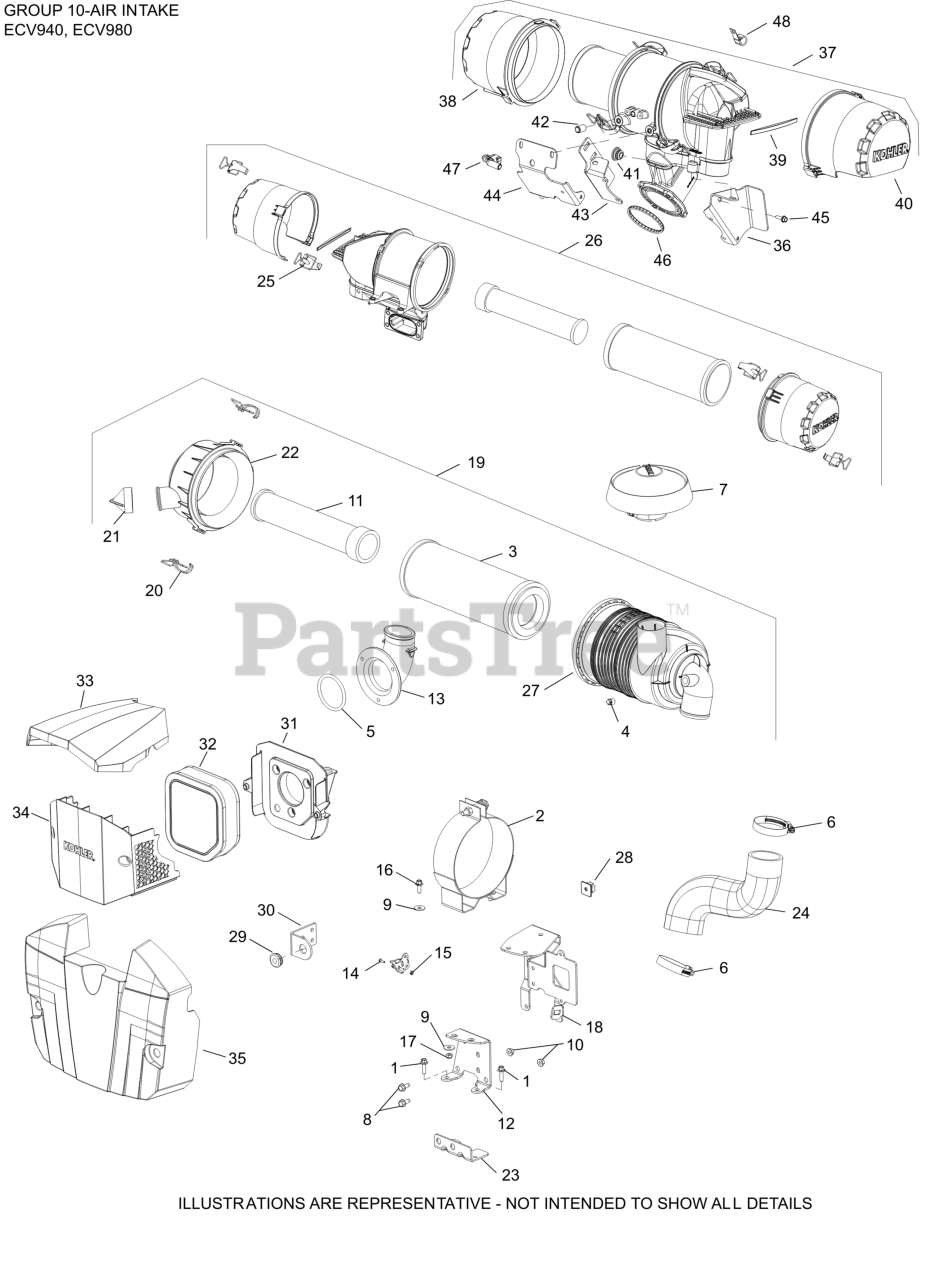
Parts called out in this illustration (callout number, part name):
1	SCREW, FLG M6x1.0x20
3	ELEMENT, AIR FILTER - PRIMARY
10	NUT, FLG M6X1.0
11	ELEMENT, AIR FILTER - SAFETY
16	SCREW, FLG M6X1.0X16
25	CLIP ASSEMBLY
36	BRACKET, AIR CLEANER & ECU MOUNTING
37	CLEANER, ASSEMBLY AIR - ETB
38	COVER, AIR FILTER
39	DAMPER, FOAM INSERT
40	COVER, RAIN CAP
42	CAP, MASKING
43	BRACKET, FUSE
44	BRACKET, AIR CLEANER
45	SCREW, HVY FLG M5X.8X16
46	O-RING (HDAC SEAL-EFI)
47	FITTING, EVAP CONNECTOR
48	CLIP, CABLE (KM)
